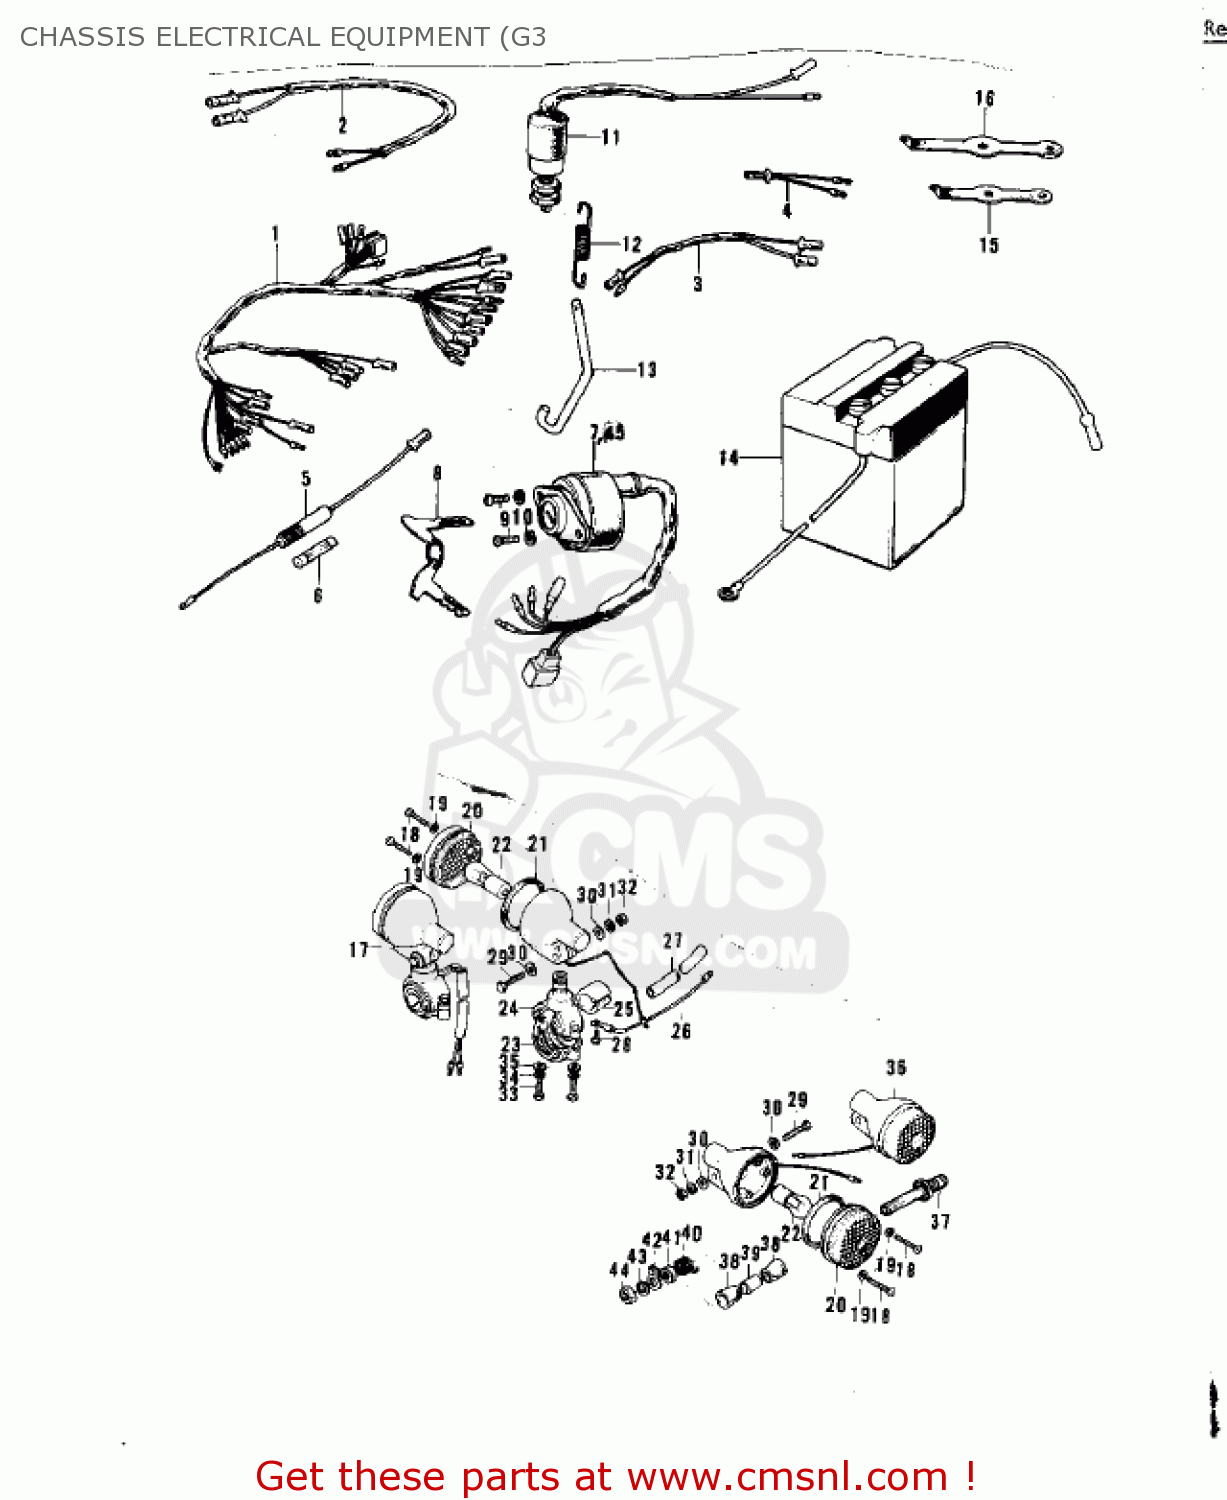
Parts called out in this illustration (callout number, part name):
1	WIRING HARNESS,MAIN
2	WIRING HARNESS-REAR
3	WIRE-LEAD
4	WIRE-LEAD
6	FUSE 10A
8	KEY SET,#321
9	SCREW-PAN-CROS
10	WASHER-SPRING,5MM
11	SWITCH-BRAKE LAMP
12	SPRING-BRAKE LAMP SW
13	HOOK-BRK LAMP SW SPRG
14	BATTERY,YUA,6N4-2A-5
15	BAND,MIDDLE
16	BAND,LONG
17	LAMP ASY-FR TURN SIG
18	SCREW-PAN HEAD,4X20
19	WASHER,PLAIN,4MM
20	LENS-SIGNAL LAMP,045-
21	GASKET,SIGNAL LAMP (NAS)
22	BULB,6V 21CP
23	BRACKET-SIGNAL LAMP,F
24	BRACKET-SIGNAL LAMP,F
25	DAMPER
26	WIRE-LEAD,SIGNAL LAMP
27	COVER-WIRING HARNESS
28	SCREW-PAN HEAD,3X5
29	BOLT-UPSET
30	WASHER-PLAIN-SMALL,6M
31	WASHER-SPRING,6MM
32	NUT,6MM
33	BOLT,5X16
34	WASHER-SPRING,5MM
35	WASHER-PLAIN,5MM
36	LAMP-SIGNAL
37	TURN SIGNAL BRACKET
38	DAMPER RUBBER
39	COLLAR
40	SPRING
41	WASHER-PLAIN
42	CLAMP-RR SIGNAL LAMP
43	WASHER-SPRING,12MM
44	NUT,12MM
45	KEY,BLANK
?	FUSE-ASSY
